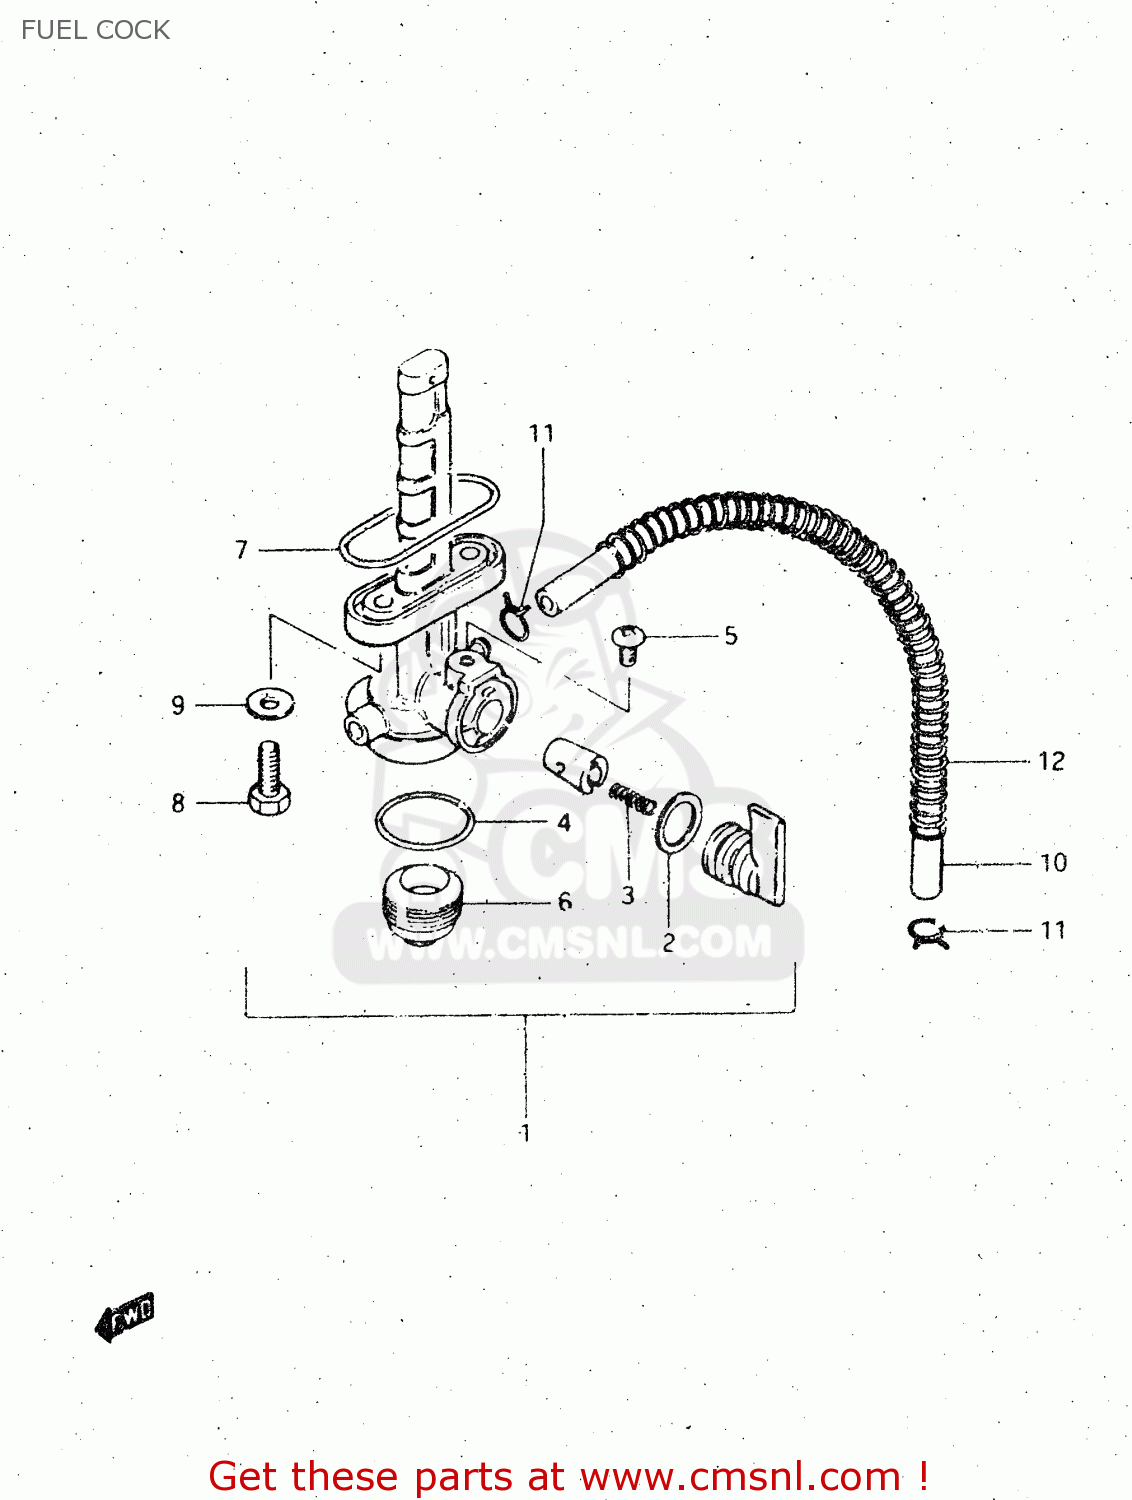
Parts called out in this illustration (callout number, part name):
1	COCK ASSEMBLY,FUEL
2	O-RING
3	SPRING
4	GASKET,FILTER (NAS)
5	SCREW,FUEL COCK LEVER
6	CUP,STRAINER
7	O RING,FUEL COCK
8	BOLT(6X20)
9	GASKET
10	HOSE
11	CLIP
12	SPRING
